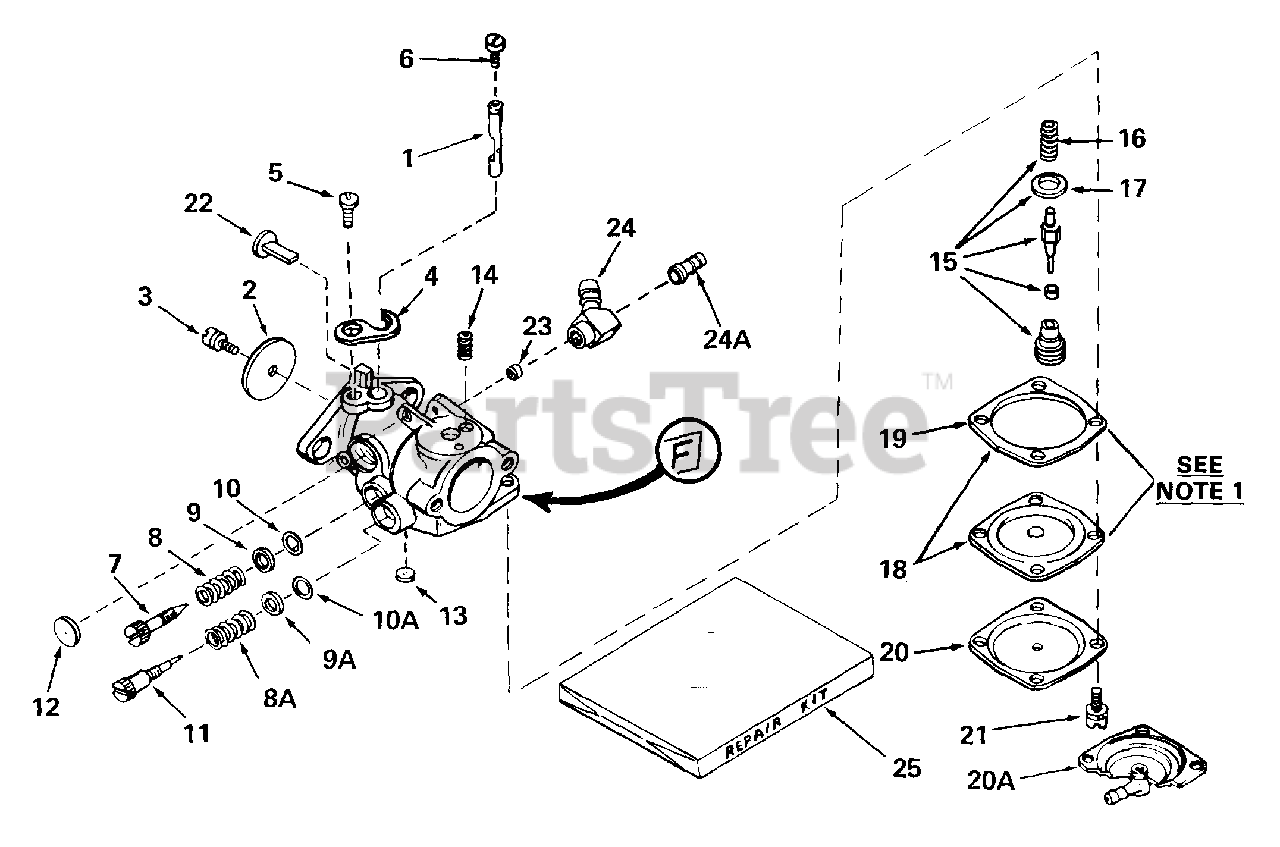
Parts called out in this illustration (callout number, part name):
1	"Shaft, Throttle
2	Shutter, Throttle
3	Screw, Shutter
6	Screw, Throttle lever
7	Screw, Idle adjustment
8	Spring, Adjustment screw
8A	Spring, Adjustment screw
9	Washer, Adjustment screw
9A	Washer, Adjustment screw
10	"O" Ring, Adjustment screw
10A	"O" Ring, Adjustment screw
11	Screw, Main adjustment
12	Plug, Welch
13	Plug, Welch
14	Spring, Choke positioning
15	Inlet Needle, Seat, Spring & Gasket A ssy.
16	Spring, Inlet needle
17	Gasket, Valve seat
18	Diaphragm Assy.
19	Gasket, Diaphragm
20	Cover, Diaphragm
21	Screw, Cover
24	Fitting, Fuel inlet
24A	Fitting, Fuel inlet
25	Repair Kit
